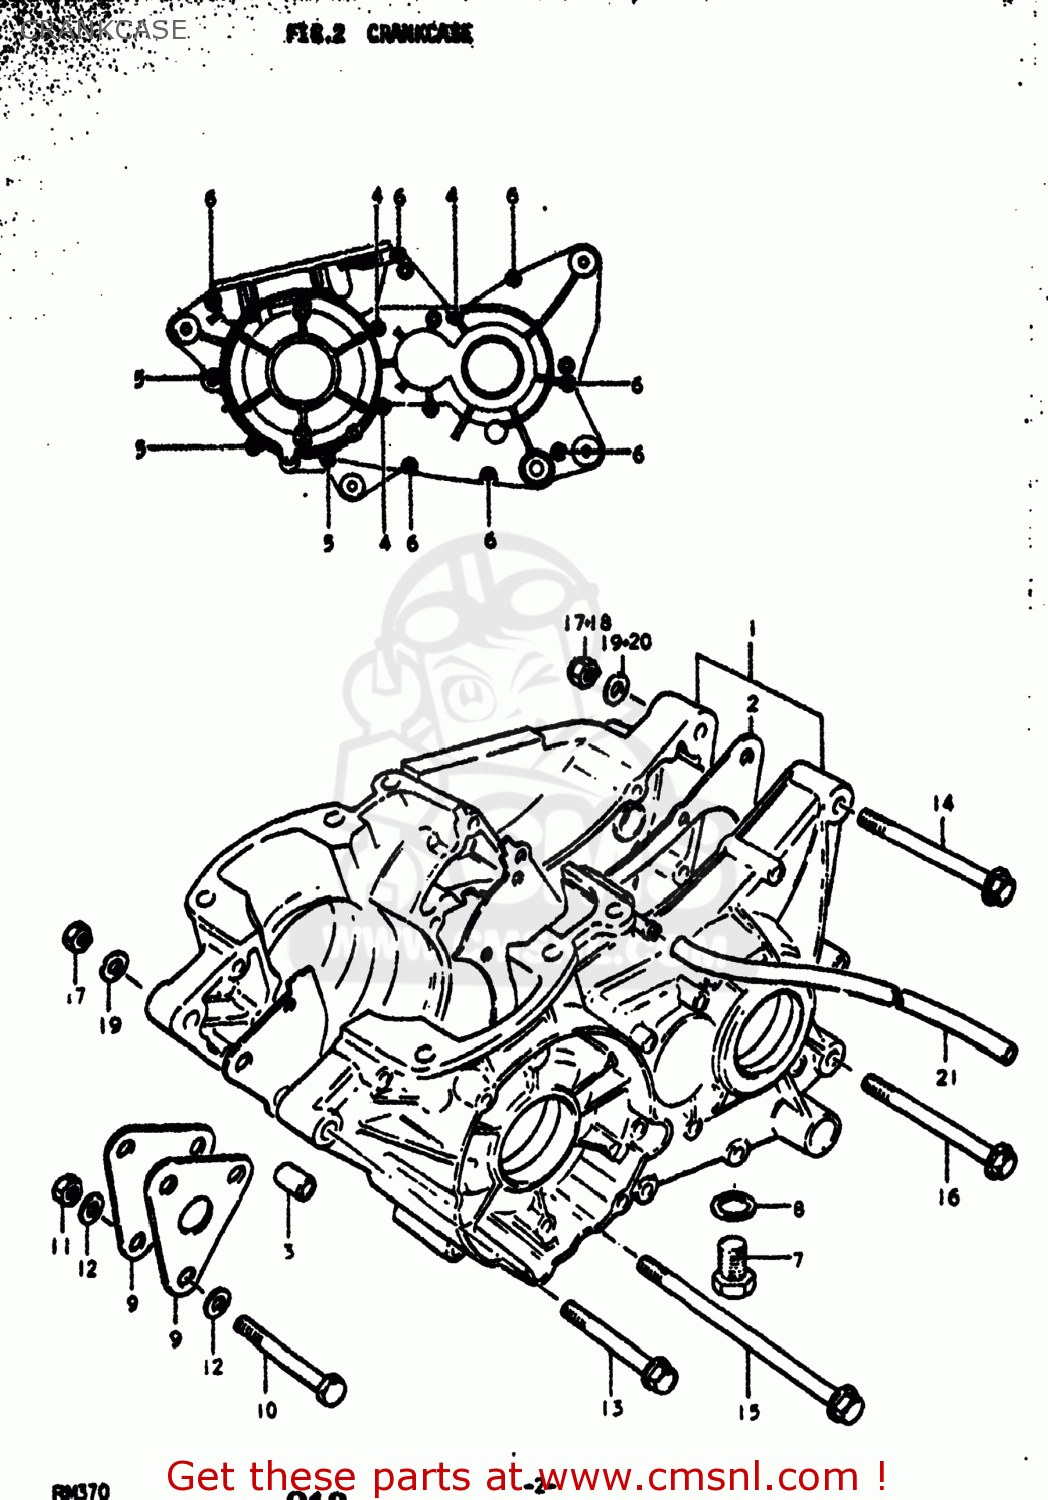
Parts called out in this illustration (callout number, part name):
1	CRANKCASE SET
2	GASKET,CRANKCASE (MCA)
3	PIN
4	SCREW 6X60
5	SCREW
6	SCREW
7	PLUG
8	GASKET(14X19.2X2) (NAS)
9	PLATE,ENGINE MOUNTING
10	BOLT
11	NUT
12	WASHER
13	BOLT
14	BOLT
15	BOLT
16	BOLT(8X80)
17	NUT
18	NUT
19	WASHER
20	WASHER
21	HOSE
